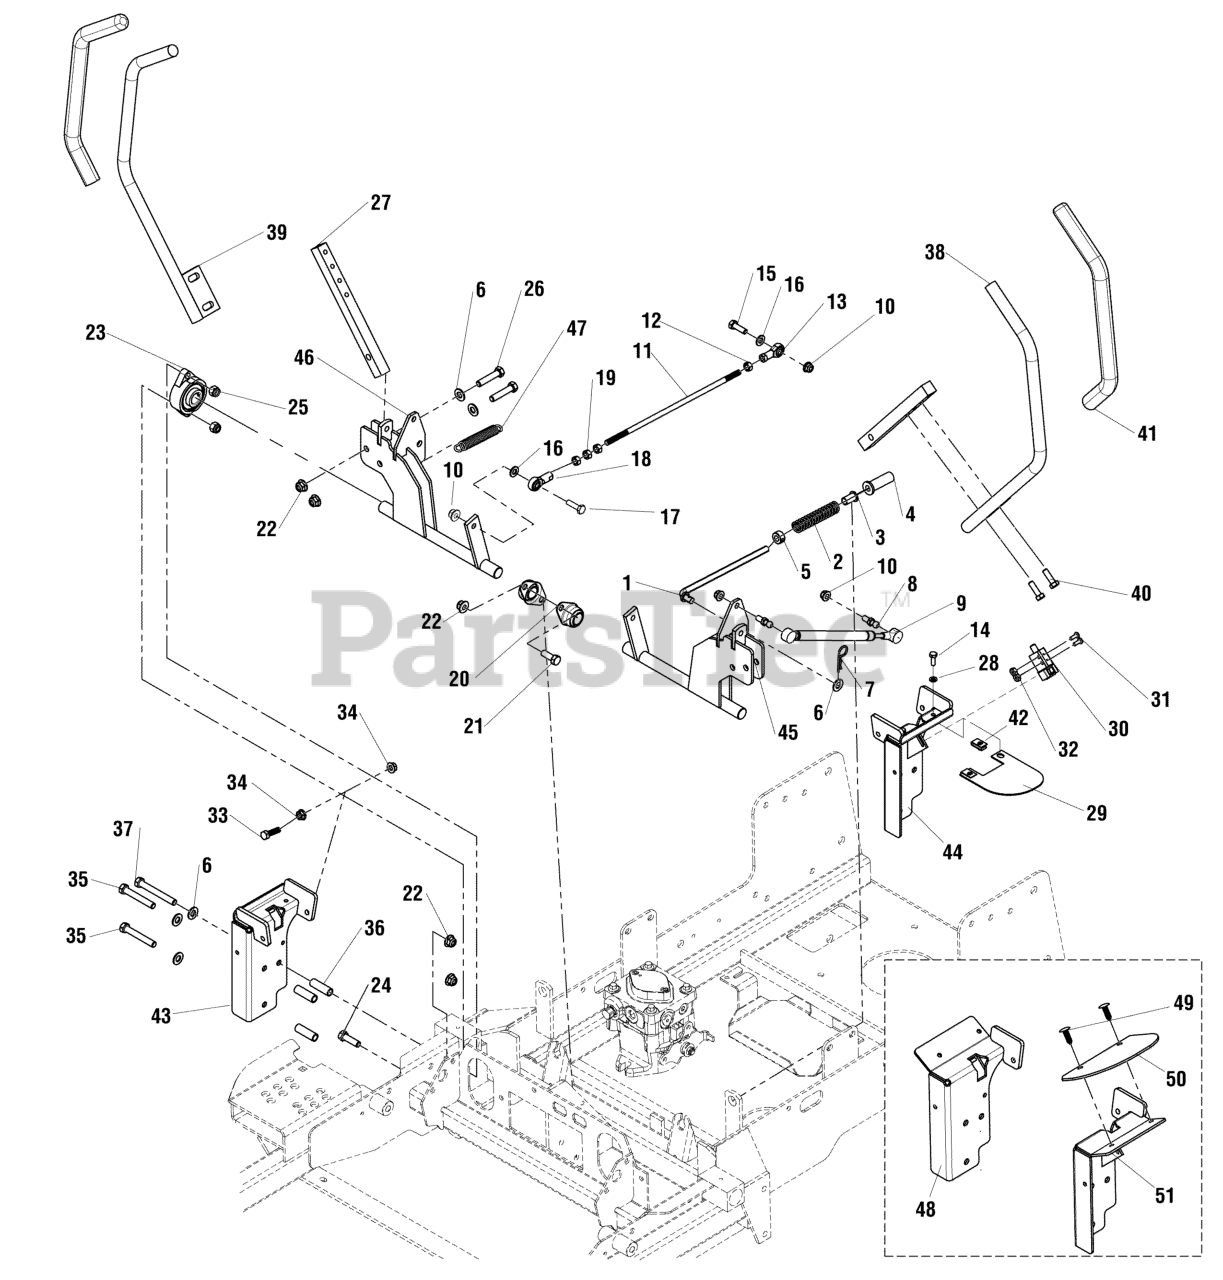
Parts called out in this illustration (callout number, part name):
1	ROD, NEUTRAL RETURN
2	SPRING, REVERSE RETURN
3	BUSHING, NYLON
4	FLANGED BUSHING, 3/8IDX.63ODX.8125FL
5	COLLAR, 3/8" SET
6	WASHER, 3/8 SAE
7	PIN, HAIR, .0915 X 1-7/8
8	BALL STUD, 5/16 X .50,# PC-477-2)
9	DAMPENER, CONTROL,#(P6709/P3610)
10	NUT, 5/16-18 HEX NYLOCK FLANGE
11	ROD, HYDRO LINKAGE
12	NUT, 5/16-24 HEX, LH
13	BALL JOINT 5/16-24 LH FEMALE BRONZE RACE
14	BOLT, 1/4-20 X 3/4"
15	BOLT, 5/16-18 X 1" GD5 YZ
16	WASHER, 5/16" SAE
17	BOLT, 5/16-18 X 1-1/4" GD5 YZ
18	BALL JOINT 5/16-24 RH FEMALE BRONZE RACE
19	NUT, 5/16-24 HEX
20	BEARING, BRONZE FLANGE, 3/4
21	BOLT, 3/8-16 X 1" GD5 CZ
22	NUT, 3/8-16 HEX NYLOCK FLANGE
23	BEARING, FLANGE
24	BOLT, 3/8-16 X 1-1/4" GD5 CZ
25	NUT, 3/8-16 HEX NYLON LOCK
26	BOLT, 3/8-16 X 1-3/4" GD5 CZ
27	MOUNT, CONTROL ARM - BLK
28	WASHER, 1/4 SAE
29	MOTION CONTROL GUARD
30	SWITCH, PLUNGER, N.O./N.C.
31	SCREW, #10-24 X 1/2" ROUND PHILLIPS
32	NUT, #10-24 HEX
33	BOLT, 5/16-18 X 1-3/4" GD5
34	NUT, 5/16-18 HEX SERRATED FLANGE (SMALL)
35	BOLT, 3/8-16 X 2-1/2" GD5 CZ
36	SPACER, .39 X .63 X 1.50
37	BOLT, 3/8-16 X 3" GD5 CZ
38	KIT, HANDLE BAR REPLACE, L/R
39	KIT, HANDLE BAR REPLACE, L/R
40	SCREW-HEX WSHR HD TAPTT5/16-18X1.000BLK
41	GRIP, FOAM, 3/4" ID, 16" LONG
42	BODY CLIP, 1/4-20
43	NEUTRAL LOCK PLATE, RH
44	NEUTRAL LOCK PLATE, LH
45	WELD, SHAFT MOTION CONTROL - LH - BLK
46	WELD, SHAFT MOTION CONTROL - RH - BLK
47	SPRING, EXTENSION
48	WELD, NEUTRAL LOCK, RH - BLK
49	PUSH RIVET (TREE TYPE), BLACK
50	GUARD, RUBBER MOTION CONTROLS
51	WELD, NEUTRAL LOCK, LH - BLK
